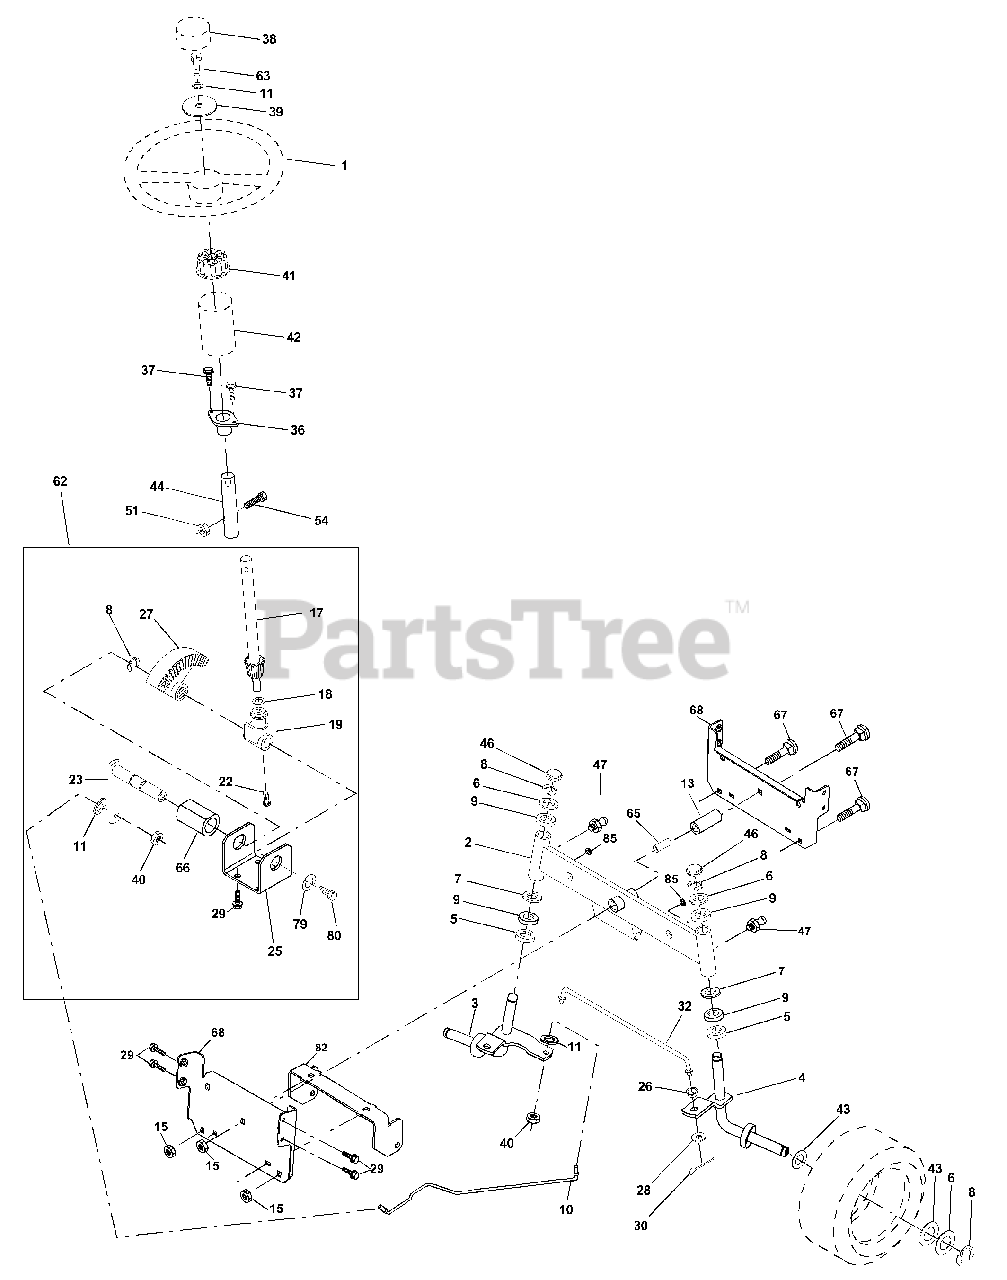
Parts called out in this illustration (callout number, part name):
1	Wheel Steering
2	Axle Asm Front
3	Spindle Asm Lh
4	Spindle Asm Rh
5	Bearing Race Thrust Harden
6	Washer 25/32 X 1 5/8 X 16ga
7	Washer 27/32 X 1 1/4 X 16 Ga
8	Ring Klip #t5304-75
9	Bearing Col Strg Blk
10	Link Drag Extended
11	Lockwasher
13	Spacer Bearing Axle Front
15	Hex Flange Lock
17	Shaft Asm Strg 5/8 X 15 19 Lt
18	Washer Thrust 515 x 750 x 033
19	Support Shaft
22	Screw Hex Wsh Hd Torx
23	Shaft Asm Pittman
25	Bracket Steering
26	Bushing Rod Tie Blk Lt
27	Gear Sector
28	Washer 13/32 X 7/8 X 16ga
29	Screw 3/8-16 x 3/4
30	Pin
32	Rod Tie Wire Form 19 75 Mech
36	Bushing Strg 5/8 Id Dash
37	Screw TT #10-32 x 5 x 3/8 Flange
38	Insert Cap Strg
39	Washer 13/32 x 2-3/8 x 12Ga
40	Locknut Center
41	Adaptor Wheel Strg 640/ 635id
42	Boot Dash Steering
43	Washer 25/32 X 1 1/4 X 16 Ga
44	Extension Steering Non-Adjust
46	Cap Spindle Fr Top Blk
47	Fitting Grease
51	Nut Lock Hex W/Ins.
54	Bolt Fin Hex 5/16-18 Unc P
62	Kit Steering Assembly Service
63	Bolt Fin Hex 3/8-16 Unc x Gr. 5
65	Spacer Brace Axle
66	Bearing Arm Pittman
67	Bolt Rdhd Sq 3/8-16 Unc x 2-3/4
68	Brace Axle
79	Washer 13/32 x 1-1/4 x 12 Ga
80	Bolt Hex Nylon 3/8-16 x 3/4
82	Bracket Susp Chassis Front
85	Fastener Christmas Tree
